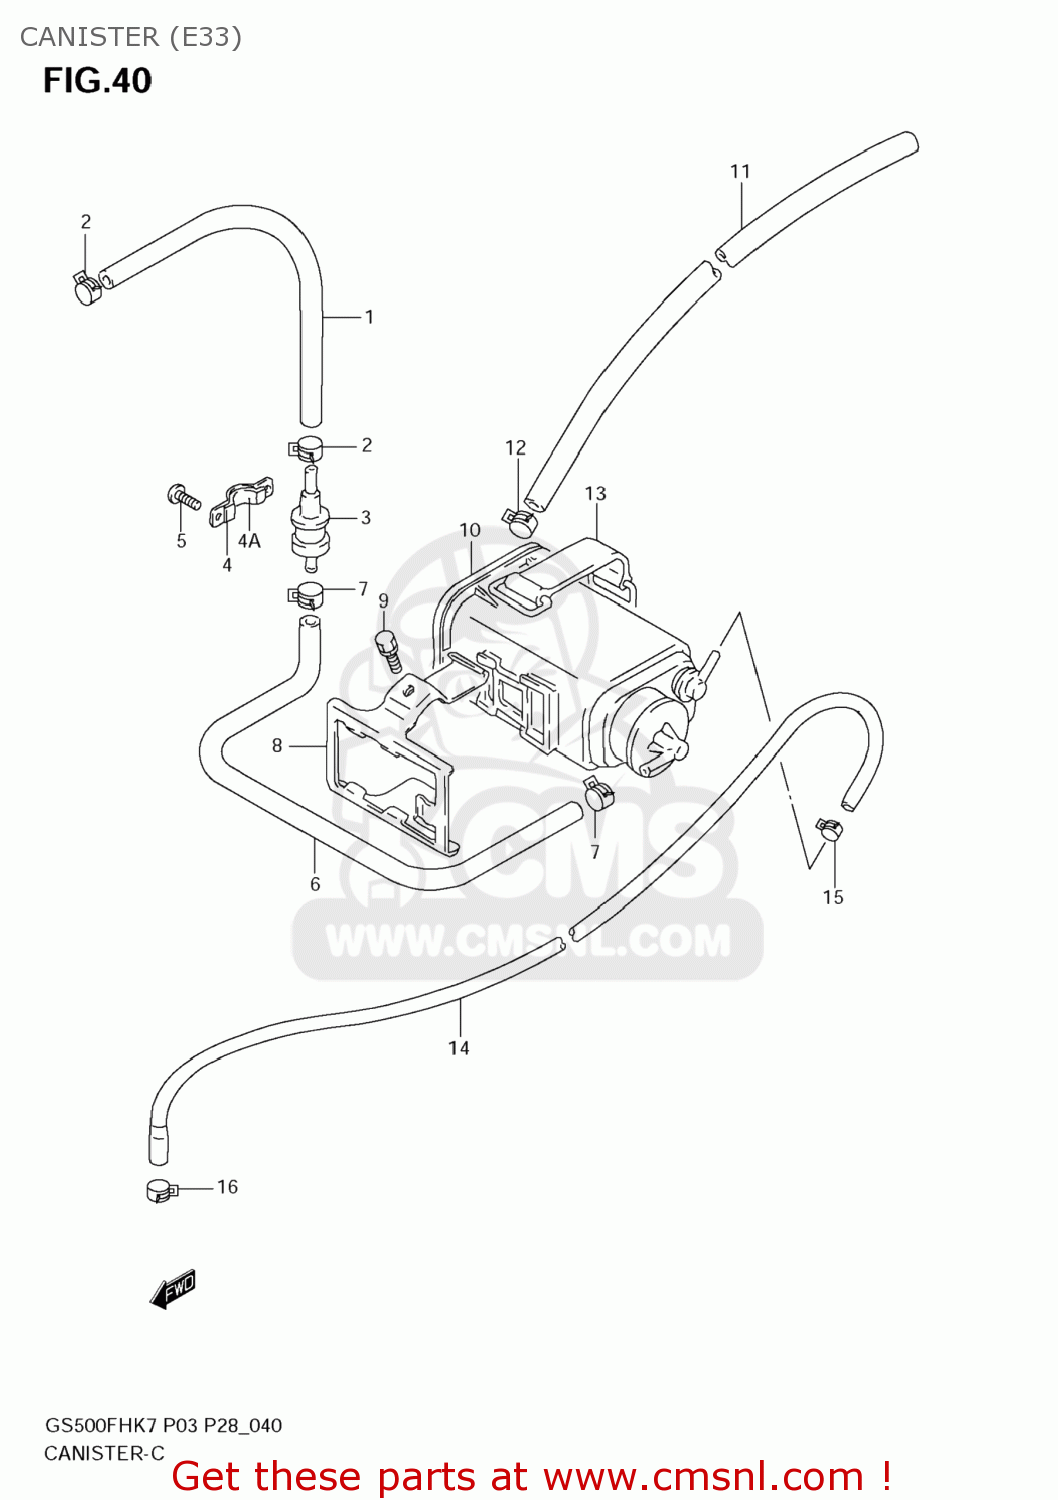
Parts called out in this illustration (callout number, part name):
1	HOSE(5.4X11.4X600)
2	CLIP
3	VALVE,FUEL TANK BREATHER
4	PLATE,FUEL TANK BREATHER NO.2
4A	CUSHION
5	SCREW
6	HOSE(5.4X11.4X350)
7	CLIP
8	PLATE,CSTR FITING
9	BOLT
10	CANISTER ASSY,CHARCOAL
11	HOSE(7X12X600)
12	CLIP
13	BAND
14	HOSE,CSTR & CARB
15	CLIP
16	CLIP
